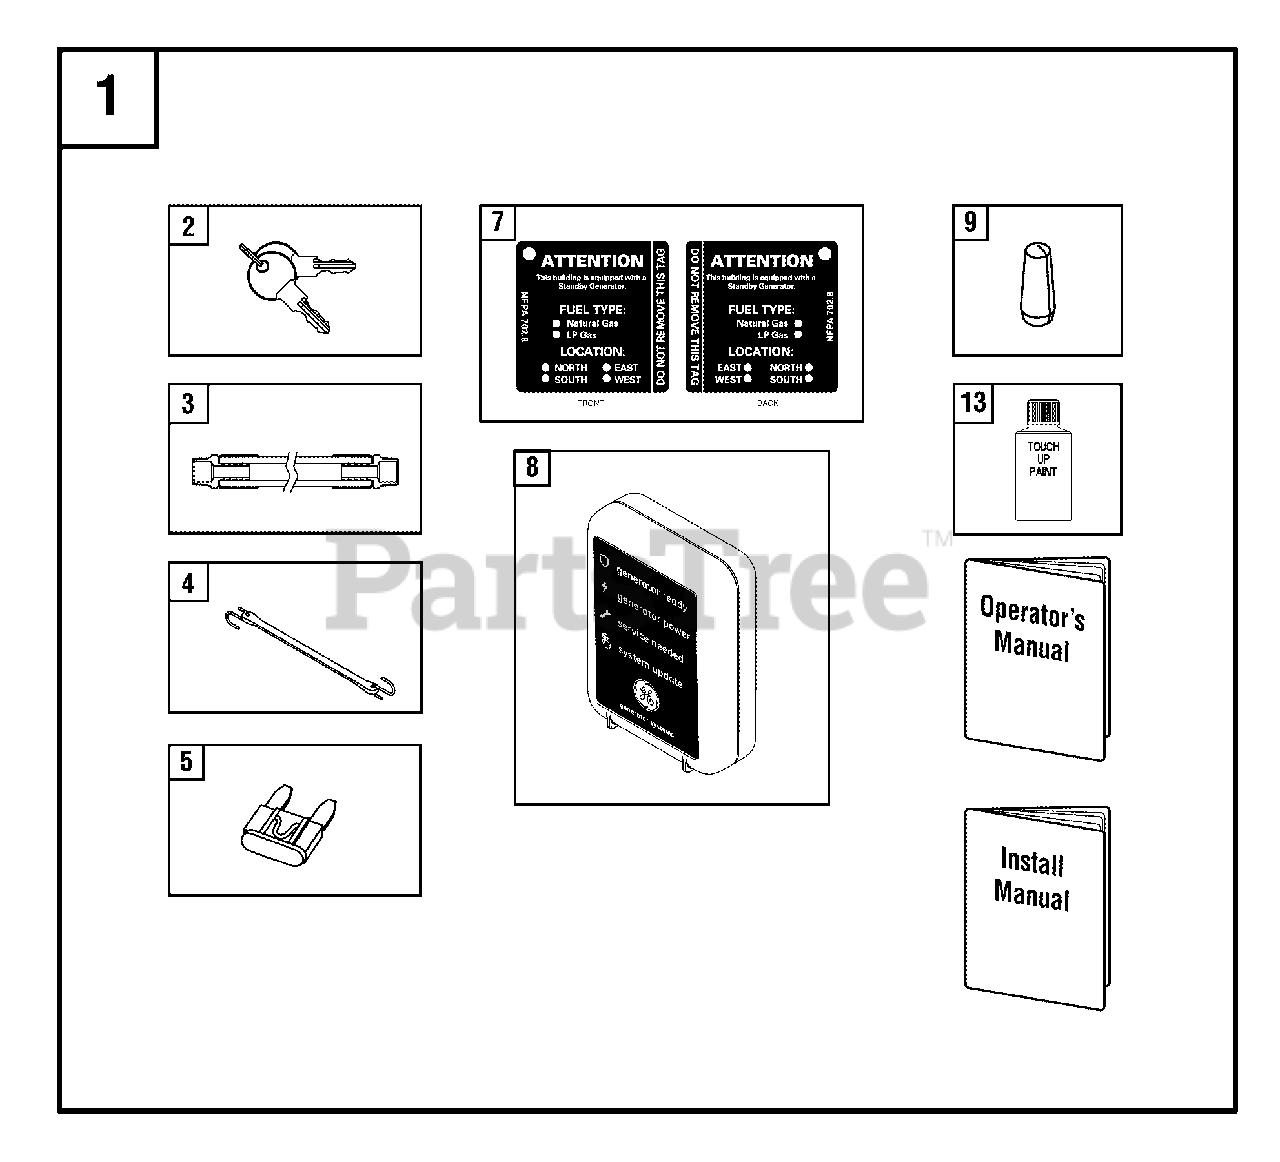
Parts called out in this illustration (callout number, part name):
1	KIT-MANUAL ACC
7	HANG TAG-ATTN. STANDBY EQUIPMENT
13	PAINT- TOUCH-UP, GE BRONZE TEXTURE
